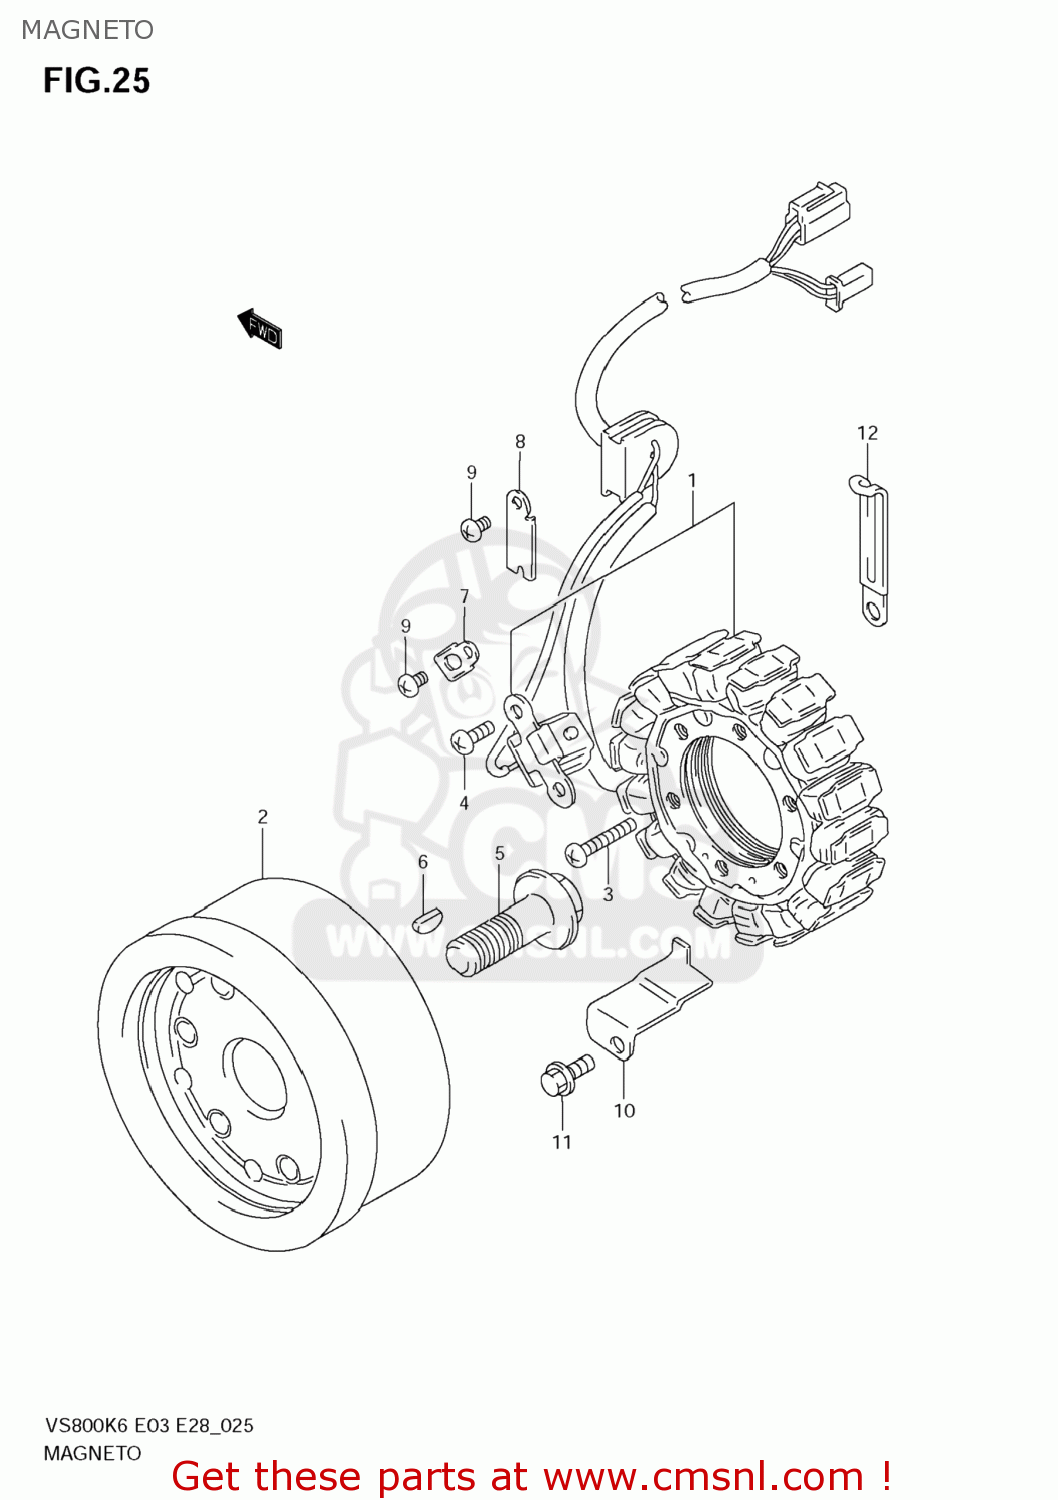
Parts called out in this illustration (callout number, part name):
1	STARTER ASSY
2	ROTOR ASSY
3	BOLT
4	SCREW
5	BOLT(14X43)
6	KEY
7	CLAMP,GENERATOR LEAD WIRE
8	CLAMP NO.1,MAGNETO READ WIRE
9	SCREW
10	CLAMP,MAGNETO LEAD WIRE
11	BOLT
12	CLAMP(L:80)
